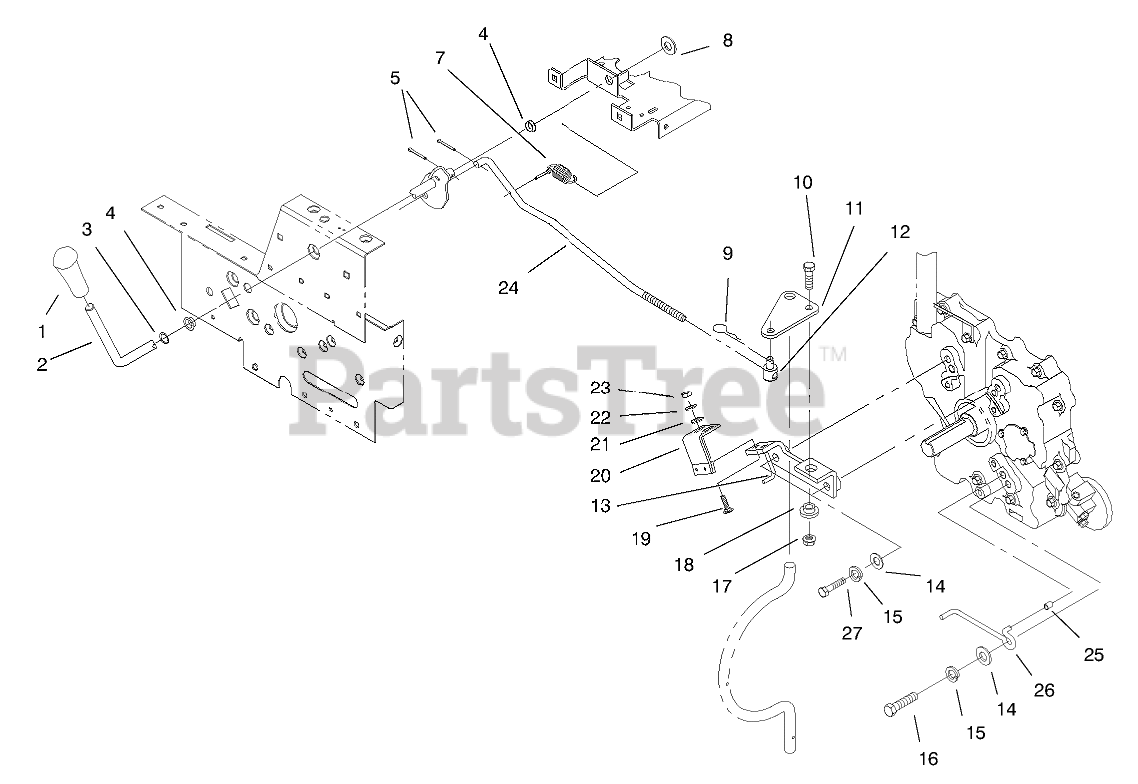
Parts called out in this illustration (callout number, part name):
2	PTO CLUTCH LEVER ASM
3	RING-EXT GRIP
4	BUSHING-NYLINER
5	PIN-COTTER
7	SPRING
8	SHIM-WASHER
9	PIN-HAIR
10	SCREW-HH
11	PLATE
12	TRUNNION
13	ENGINE BRKT ASM
14	WASHER-FLAT
15	WASHER-LOCK
16	SCREW-HH
17	NUT-LOCK, NI
18	SPACER-LIFT LINK
19	SCREW-CARR
20	BRAKE ASM
21	WASHER-FLAT
22	WASHER-LOCK
23	NUT-JAM
24	ROD-PTO CLUTCH
26	WIRE-GUIDE, BELT
27	SCREW-HH
